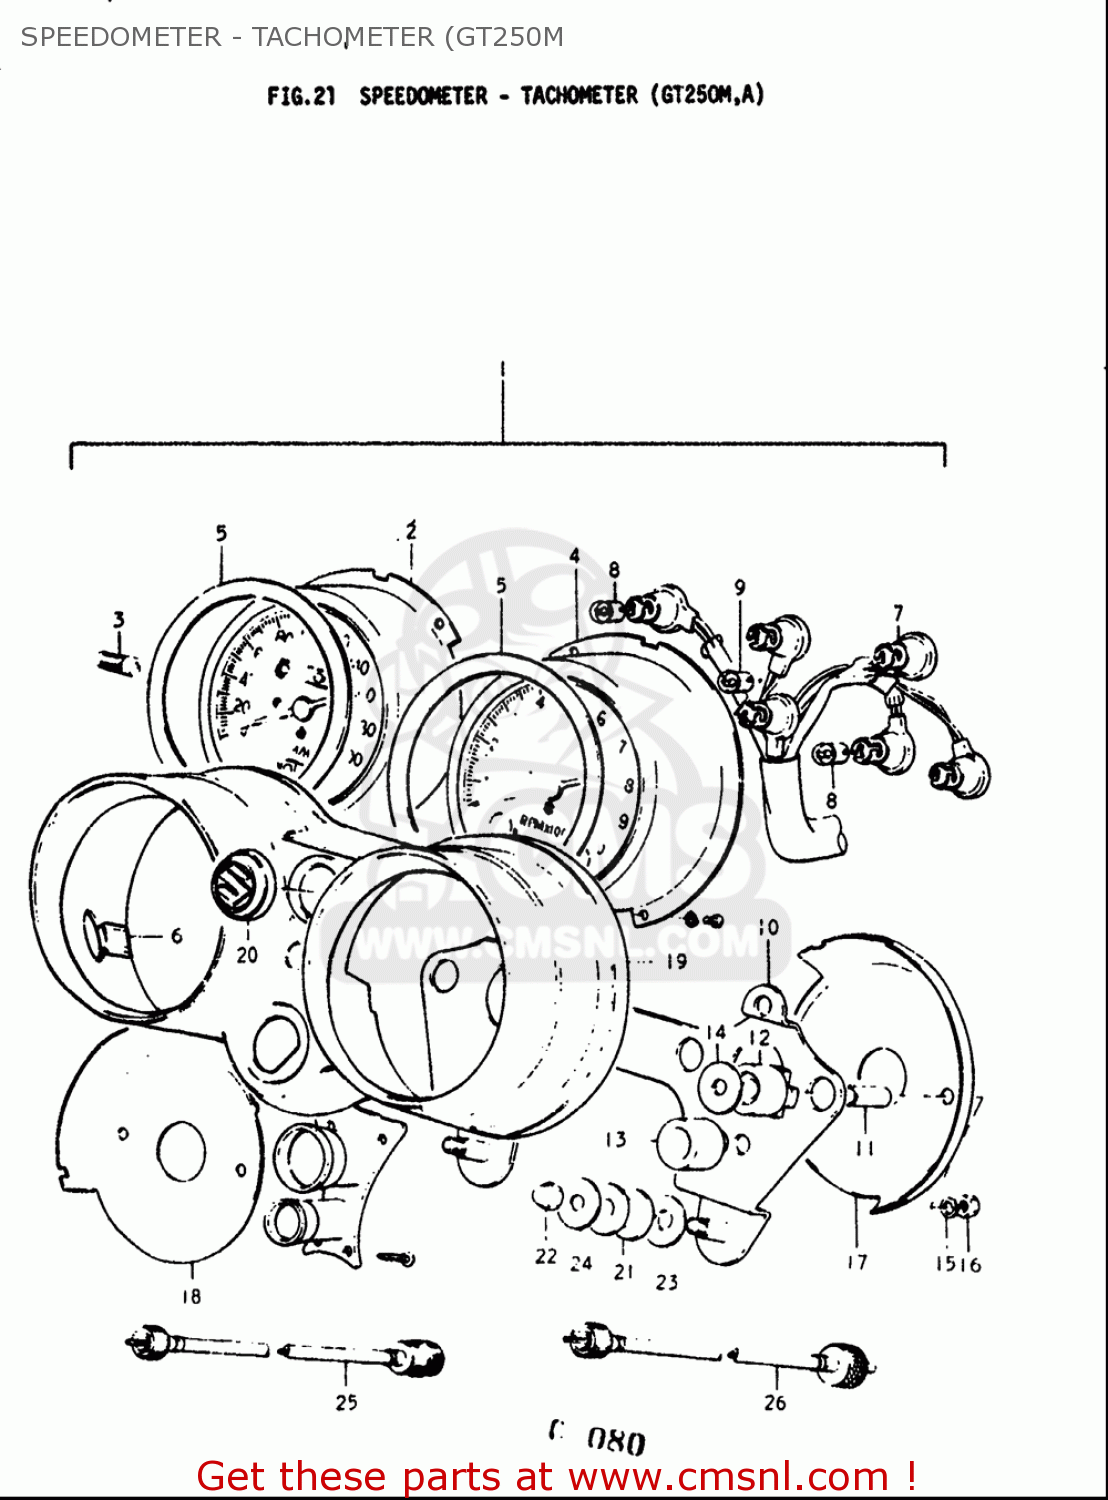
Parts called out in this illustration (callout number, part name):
3	KNOB, TRIP METER
6	CAP
8	BULB(12V3.4W,STANLEY,A72A)
9	BULB(12V1.7W,A71A)
12	CUSHION,METER NO.1
13	CUSHION,METER
14	WASHER(5.5X16X1.5)
15	WASHER,LOCK
16	NUT
20	CAP,SPEED WARNER LAMP HOLE
21	CUSHION
22	NUT
23	WASHER
24	WASHER(6.5X18X1.6)
25	CABLE ASSY,SPEEDOMETER
26	CABLE ASSY,TACHOMETER
